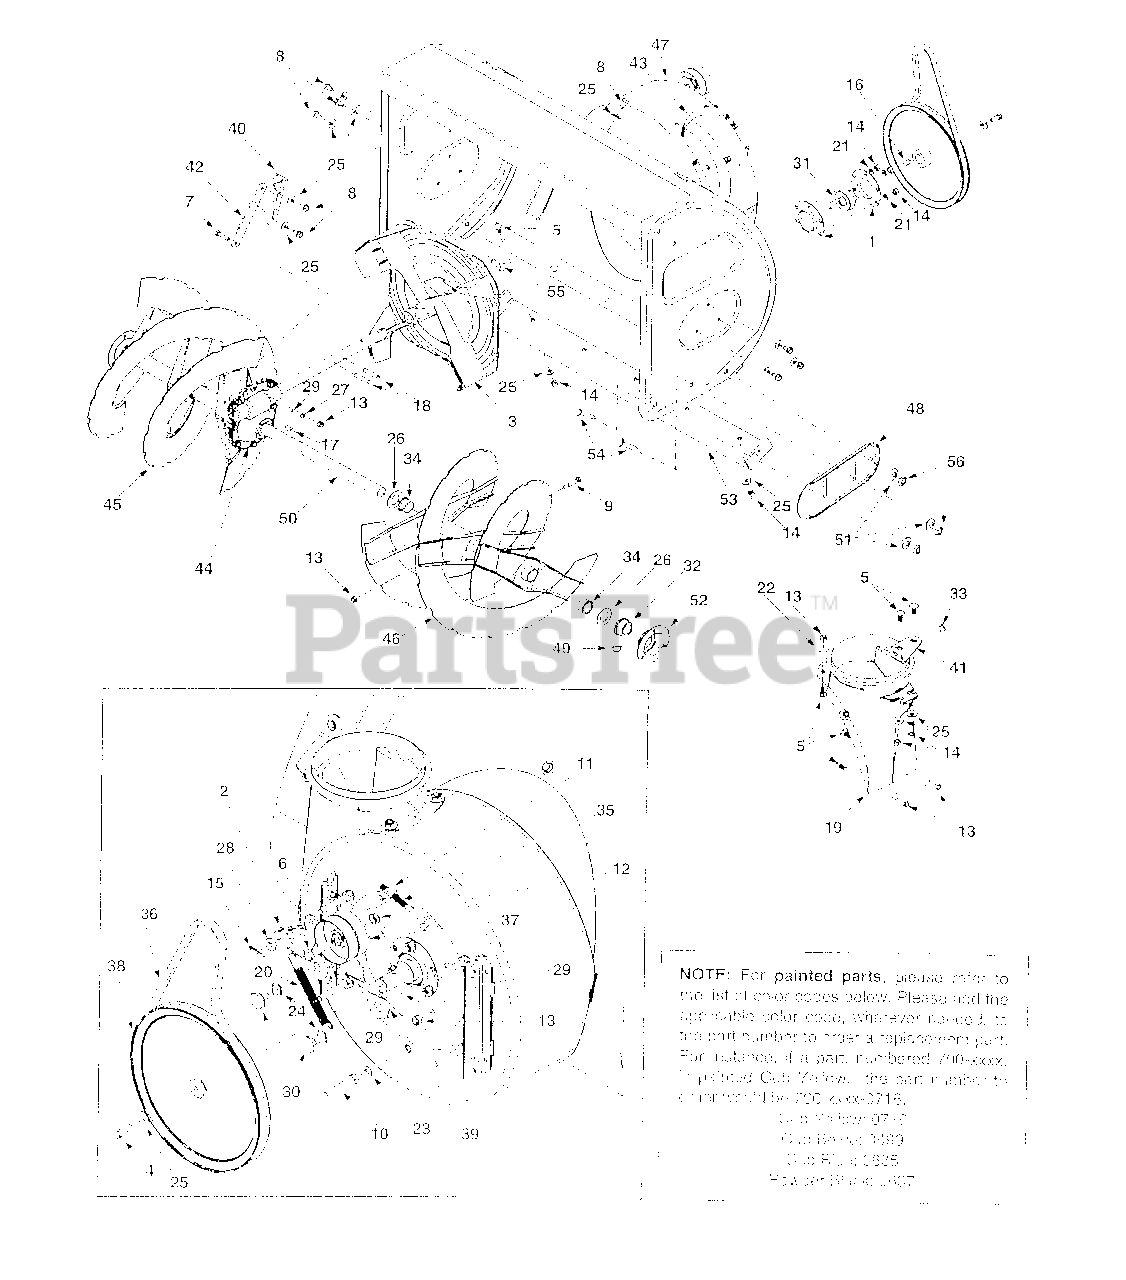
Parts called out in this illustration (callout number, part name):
1	Bearing Housing
2	Bracket Assembly: Auger Break
5	Carriage Bolt 5/16-18 x .750"
6	Hex Screw, Special 3/8-24 x 1.5"
7	Hex Screw 5/16-18 x 1.25"
8	Self-Tapp. Screw 5/16-18 x .625"
9	Shear Bolt 5/16-18 x 1.75"
11	Ferrule
12	Jam Nut 3/8-24
13	Hex Lock Nut 5/16-18
14	Hex Nut 5/16-18
15	Hairpin Clip
18	Spiral Pin
19	Chute Adapter
20	Extension Spring
21	Lock Washer
22	5/16 Washer
23	Lock Washer
24	Wave Washer
25	Beleville Washer
26	Flat Washer
27	Spring Washer
28	Flat Washer
30	Shoulder Screw
31	Self-Aligning Bearing
32	Flange Bearing w/ Flats
33	Plastic Bushing
34	Flange Bushing
35	Idler Rod: Auger
36	V-Belt
37	Flat Idler
49	Lube Fitting
50	Spiral Axle
51	Bell Washer
54	Carriage Screw
55	Carriage Bolt
56	Hex Nut 3/8-16
